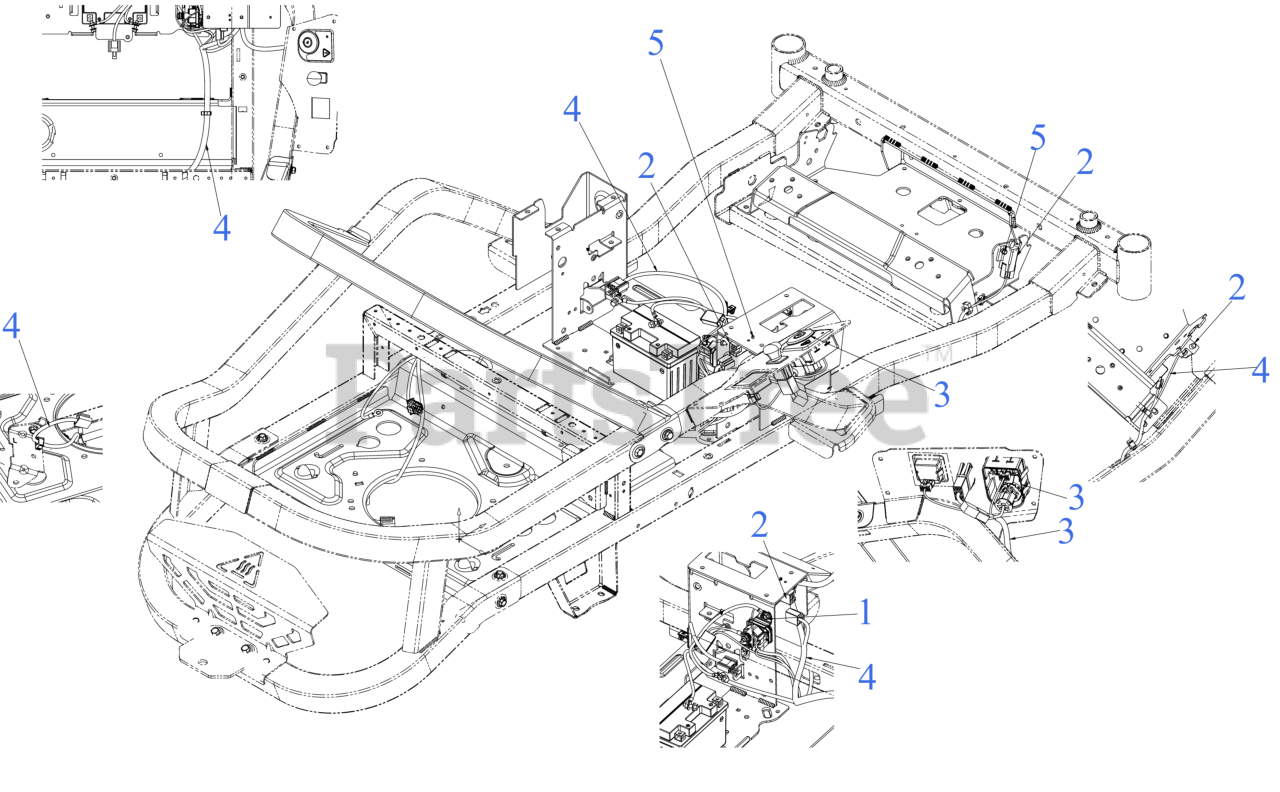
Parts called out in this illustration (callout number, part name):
1	SCREW 1/4-20X.625
2	INTERLOCK SWITCH (NO/NC)
3	IGNITION MODULE SWITCH (RMC ELC PTO WHTE)
4	MAIN HARNESS (RMC/LIGHT/H1)
5	SHOULDER SCREW
